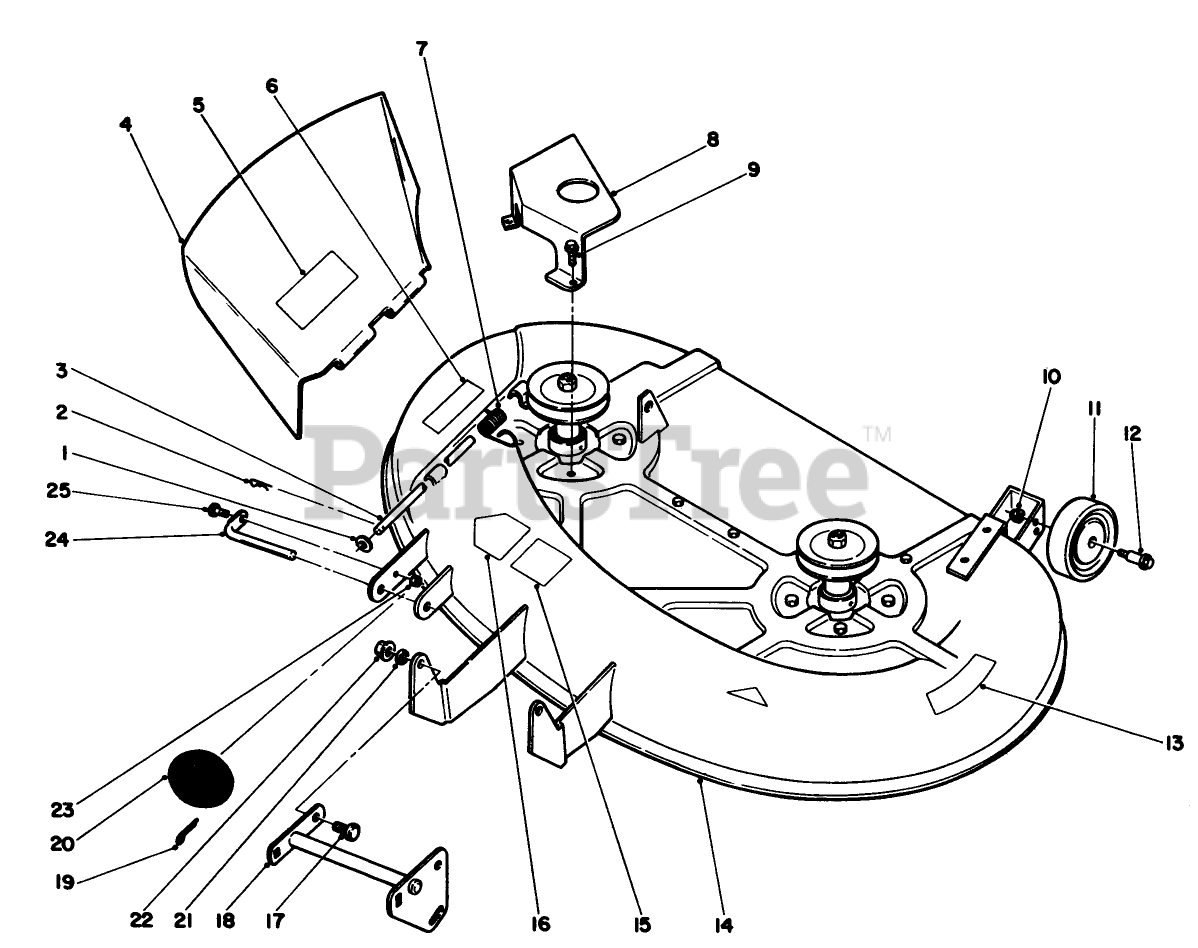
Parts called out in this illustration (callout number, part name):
1	WASHER-PLAIN
2	PIN-COTTER
4	Deflector
5	HOSE CLAMP R
6	DECAL-DANGER
7	SPRING-TORSION
8	COVER-BELT R
9	SCREW-HWHTF
10	NUT-LOCK, NI
11	WHEEL-DECK
12	BOLT-WHEEL
13	DECAL - DANGER
14	Deck W.A.
15	Decal-Routing
16	DECAL-DANGER
17	SCREW-CARR
18	ASM-FRONT LIFT R
19	PIN-COTTER
20	ROLLER
21	SPACER
22	LOCKNUT-FLANGE
23	NUT-LOCK, NI
24	SHAFT-ROLLER
25	SCREW-HH
